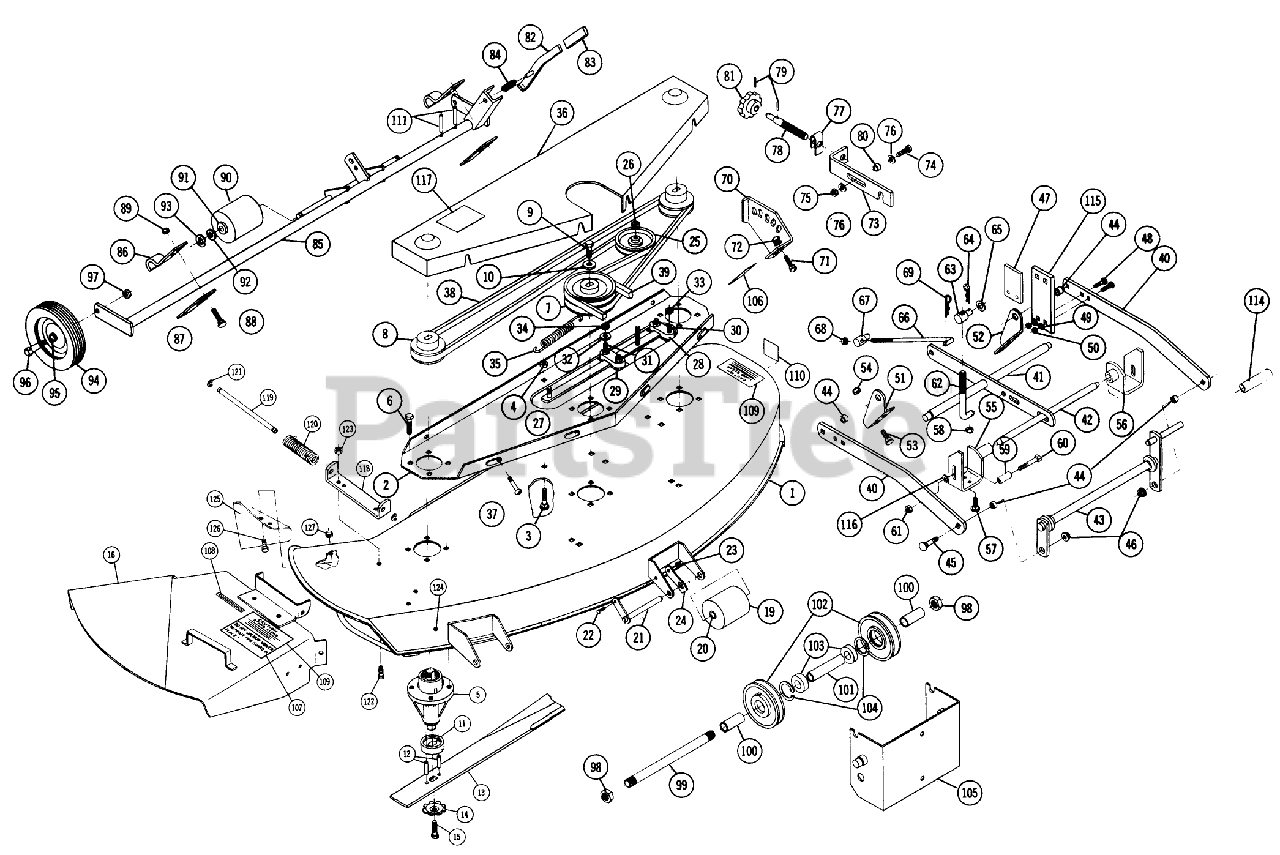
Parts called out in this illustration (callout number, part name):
5	SVC BULLT 211
10	WASHER
12	SPIROL ROLL PIN
20	BUSHING
32	WASHER 5/16 SAE
35	SPRING *R
38	V-BELT
39	V BELT
44	SPACER
47	BUMPER
62	LIFT ROD
64	Hairpin Cotter
66	ROD-LEVELER
67	TRUNNION-LIFT
69	Hairpin
79	PIN-ROLL
80	SPACER
81	KNOB-ADJUSTMENT
84	SPRING-COMPRESSION
95	BEARING
96	BOLT-SHOULDER
103	BEARING-BALL
104	Ring-Snap
111	PIN-SPIROL
114	GRIP
115	PLATE-BUMPER *R
116	WASHER
